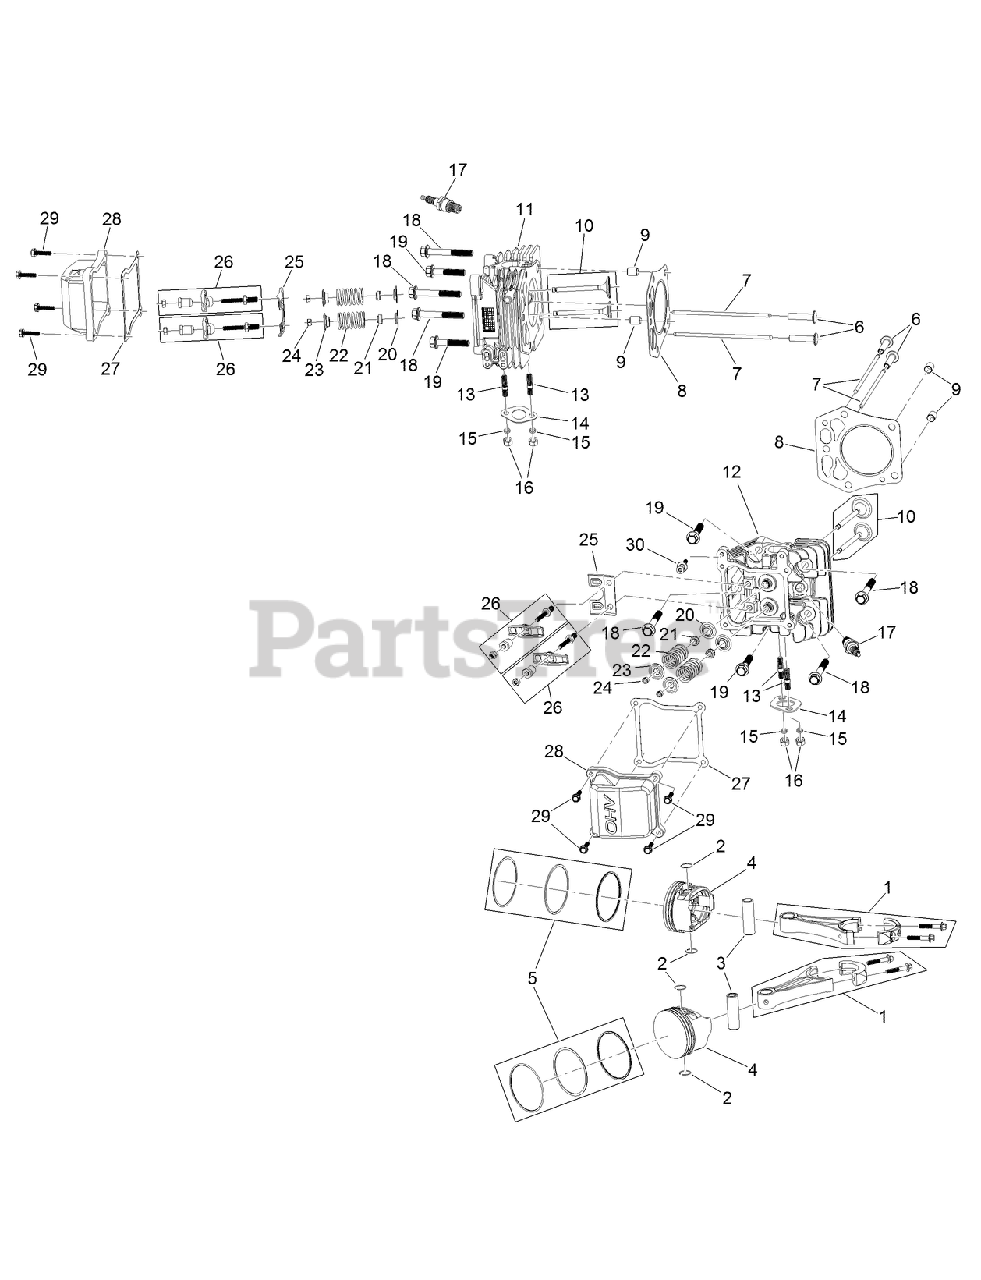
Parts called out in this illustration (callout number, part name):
1	CONNECTING ROD ASM
2	CLIP-PIN, PISTON
3	PIN-PISTON
4	PISTON
5	PISTON RING SET
6	LIFTER-VALVE
7	ROD-PUSH
8	GASKET-HEAD, CYLINDER
9	PIN-DOWEL
10	VALVE SET
11	HEAD-CYLINDER
12	HEAD-CYLINDER
14	GASKET-EXHAUST
15	WASHER-LOCK, SPLIT
16	NUT-HH
17	SPARK PLUG
18	SCREW-HWH
19	SCREW-HWH
20	SEAT-SPRING, VALVE
21	SEAL-STEM, VALVE
22	SPRING-VALVE
23	RETAINER-SPRING, VALVE
24	KEEPER-VALVE
25	PLATE-GUIDE, PUSH ROD
26	ROCKER ARM ASM
27	GASKET-VALVE COVER
28	COVER-VALVE
29	SCREW-HHF
30	SCREW-SHOULDER, HH
